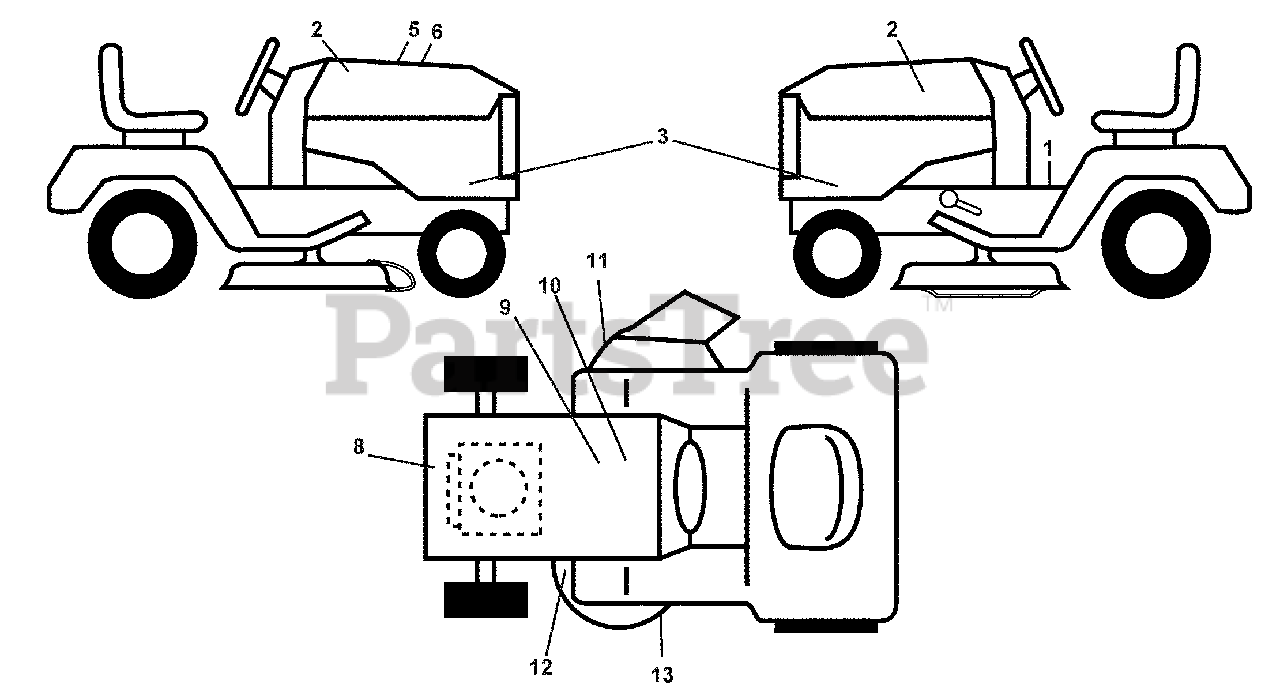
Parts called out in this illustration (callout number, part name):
1	Decal, Operators
2	Decal, Hood
3	Decal, Hood Panel SD
5	Decal, Customer Respons.
6	Decal, Replacement
8	Decal, Eng. HP
9	Decal, Battery Dnge/Poi
10	Decal, Battery
11	Warning
12	Mower Caution
13	Mower V-Belt Schematic
